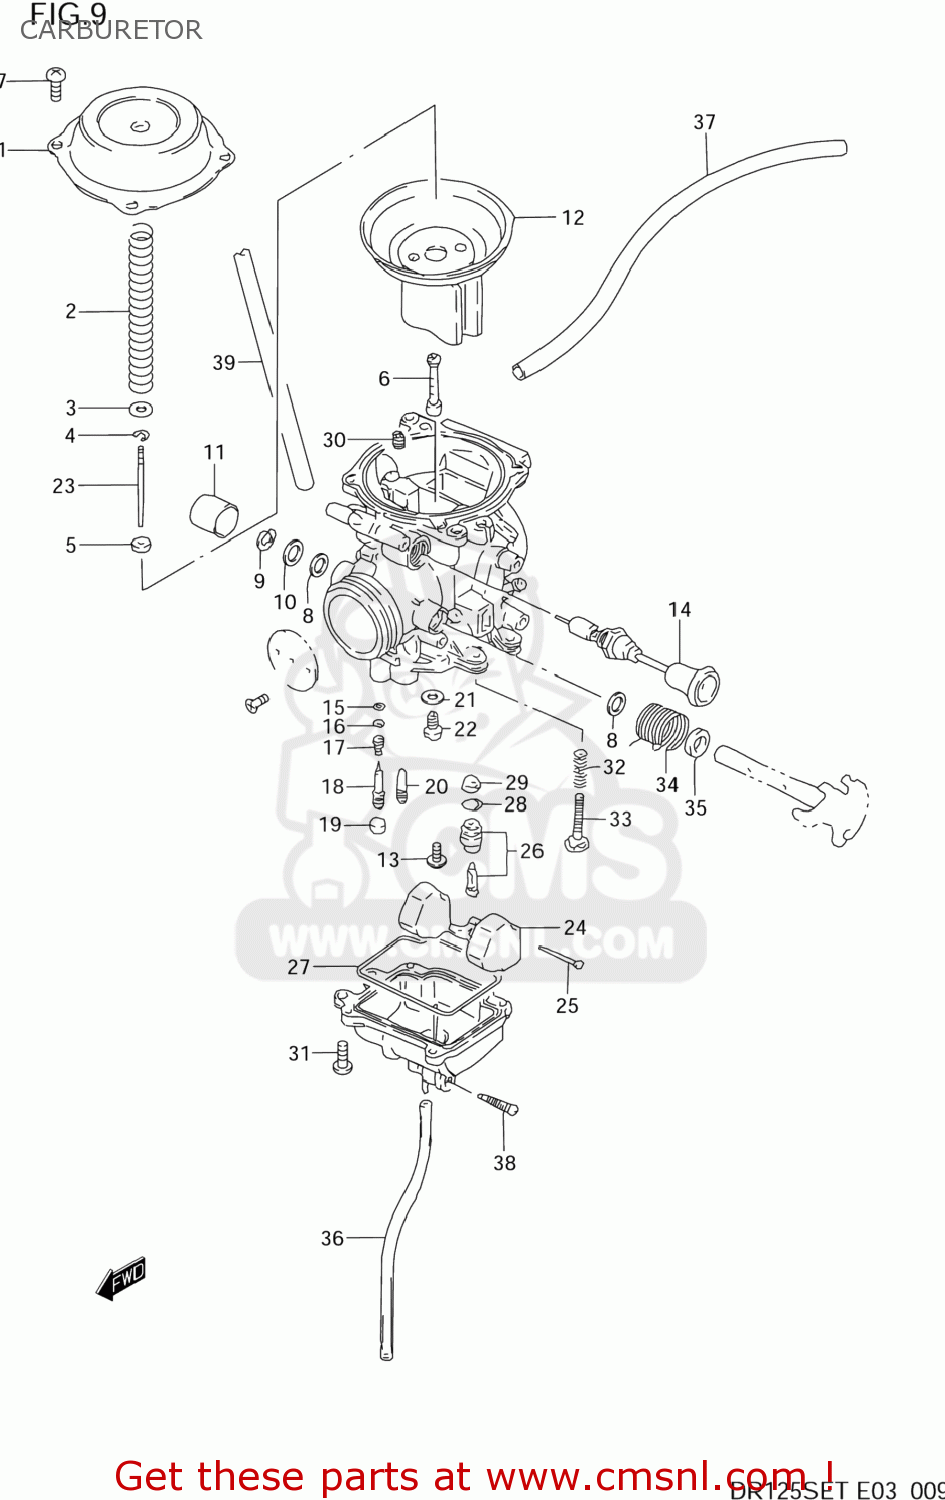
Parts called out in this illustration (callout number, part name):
1	COVER,DIAPHRAGM
2	SPRING
3	RING
4	CLIP
5	RING
6	JET,NEEDLE(P-5)
7	SCREW
8	SEAL,THROTTLE SHAFT
9	E RING
10	GASKET,THROTTLE SHAFT (NAS)
11	CAP
12	DIAPHRAGM ASSY
13	SCREW
14	PLUNGER ASSY
15	O RING,PILOT AIR SCREW
16	WASHER
17	SPRING
18	SCREW,PILOT
19	PLUG
20	JET(40)
21	WASHER,NEEDLE NOZZLE
22	JET,MAIN(112.5)
23	NEEDLE,JET(J8-5D65)
24	FLOAT
25	PIN,FLOAT
26	VALVE ASSY,NEEDLE
27	O RING,FLOAT CHAMBER
28	O-RING,NEEDLE VALVE
29	FILTER
30	JET,AIR(140)
31	SCREW
32	SPRING,THROTTLE SCREW
33	SCREW,THROTTLE STOP
34	SPRING
35	RING
36	HOSE(3X5X650)
37	HOSE(5X8.2X600)
38	SCREW,DRAIN
39	HOSE (4.5X8.5X600)
